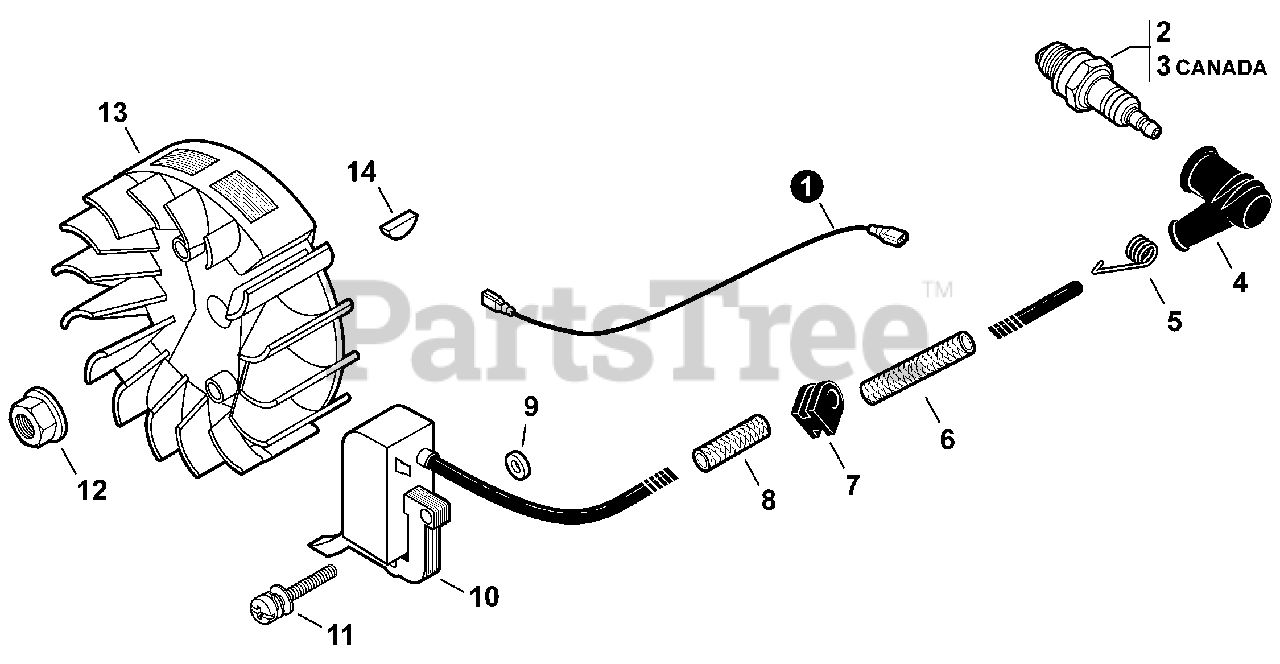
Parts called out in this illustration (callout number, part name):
1	LEAD - IGNITION L300
2	SPARK PLUG - BPM8Y
3	SPARK PLUG - BPMR8Y
4	CAP, SPARK PLUG
5	TERMINAL, SPARK PLUG
6	TUBE, INSULATOR 7×8.6×40
8	TUBE, INSULATOR
9	WASHER 5.2×12×3
10	COIL, IGNITION
11	SCREW 5×20
12	NUT, FLANGE M8
13	FLYWHEEL
14	KEY, WOODRUFF
